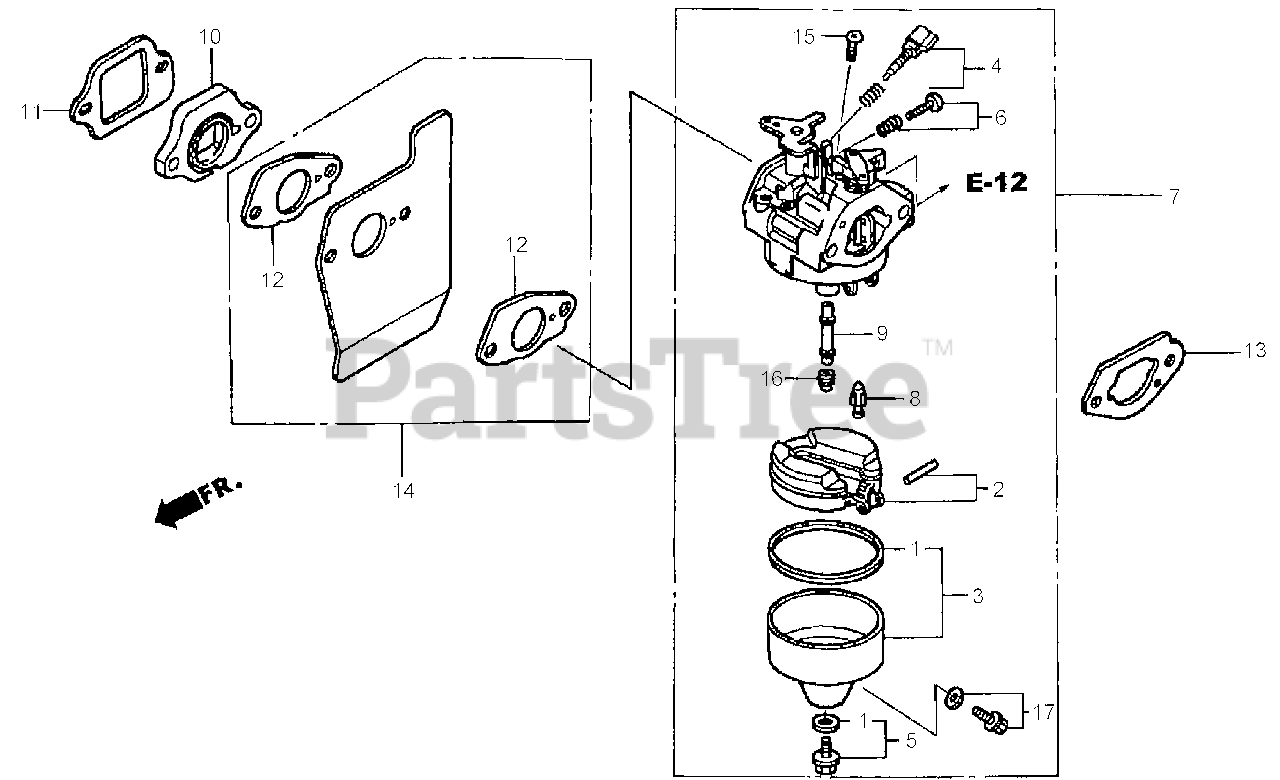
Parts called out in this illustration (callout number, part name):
1	GASKET SET
2	FLOAT SET
3	CHAMBER SET-FLOAT
4	SCREW SET (CARBURETOR NO.)
5	SCREW-SET
6	SCREW SET (CARBURETOR NO.)
7	CARBURETOR ASM (BB62B E)
8	VALVE-FLOAT (CARBURETOR NO.)
9	NOZZLE-MAIN
10	INSULATOR-CARBURETOR
11	GASKET-INSULATOR
12	GASKET-CARBURETOR
13	GASKET-CARBURETOR (CHOKE SIDE)
14	GUIDE-AIR
15	SCREW-PAN (5X6)
16	JET-MAIN (#60)
16	JET-MAIN (#62)
16	JET-MAIN (#65)
17	SCREW SET-DRAIN
